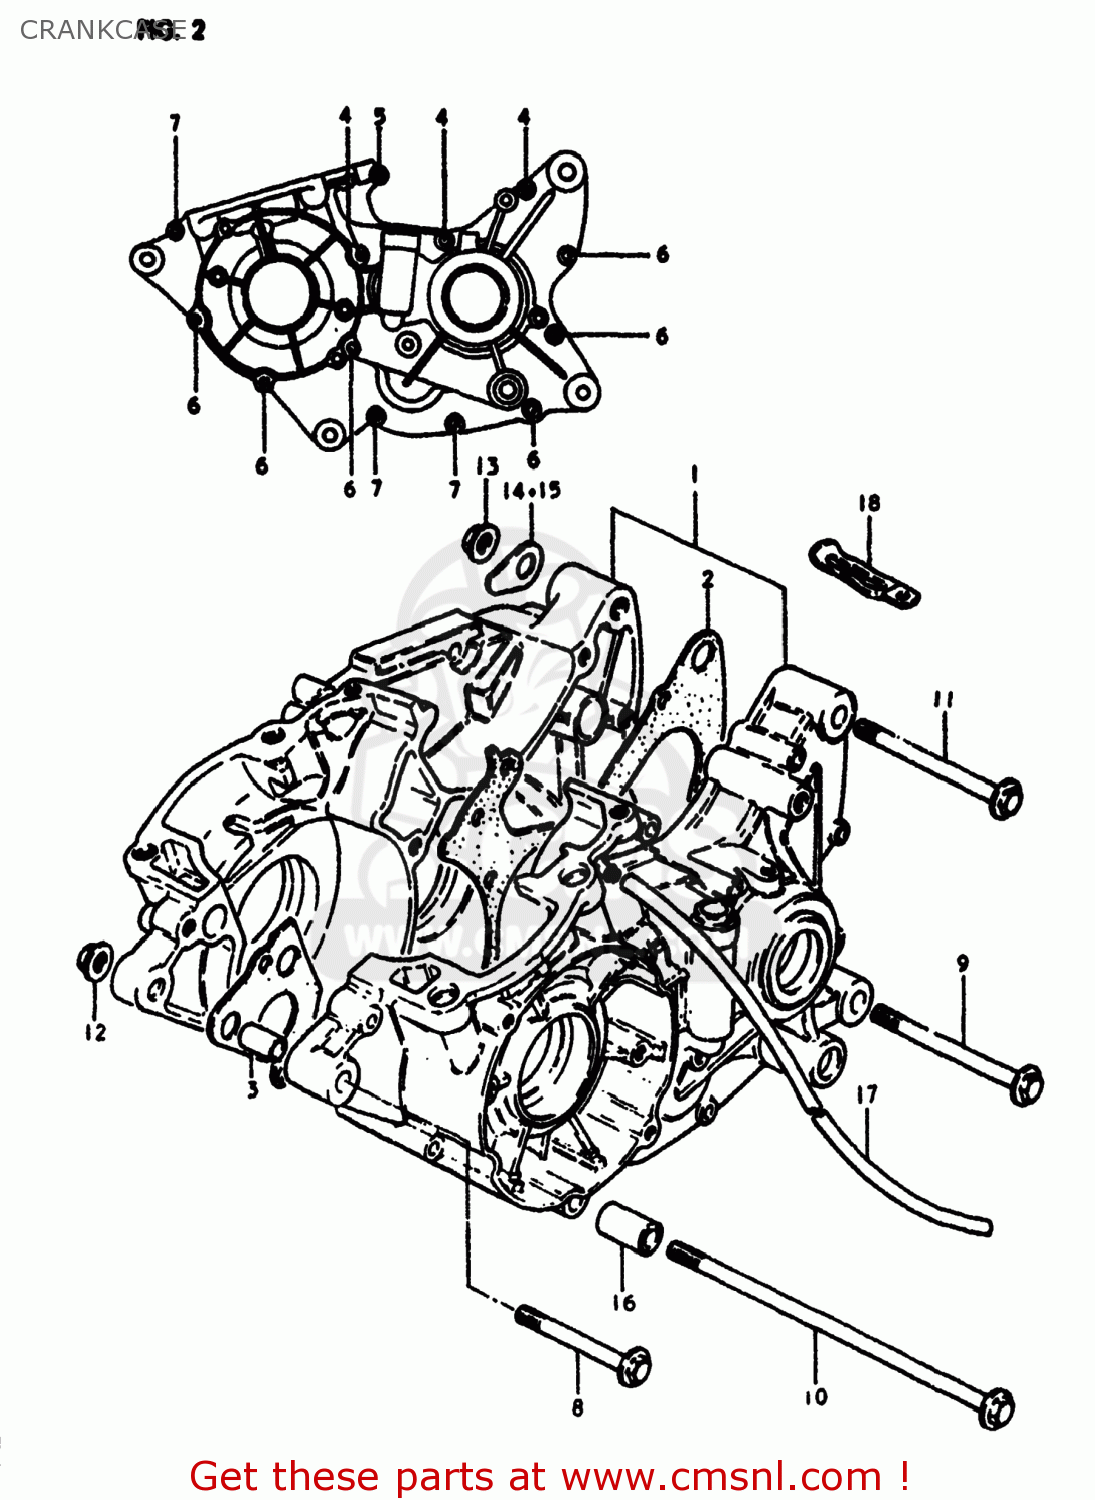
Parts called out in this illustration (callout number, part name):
1	CRANKCASE SET
2	GASKET,CRANKCASE (MCA)
3	PIN
4	SCREW 6X65
5	SCREW
6	SCREW
7	SCREW (6X35)
8	BOLT(8X67)
9	BOLT
10	BOLT
11	BOLT
12	NUT
13	NUT
14	WASHER
15	WASHER
16	SPACER(8.6X16X26)
17	HOSE
18	CLAMP
